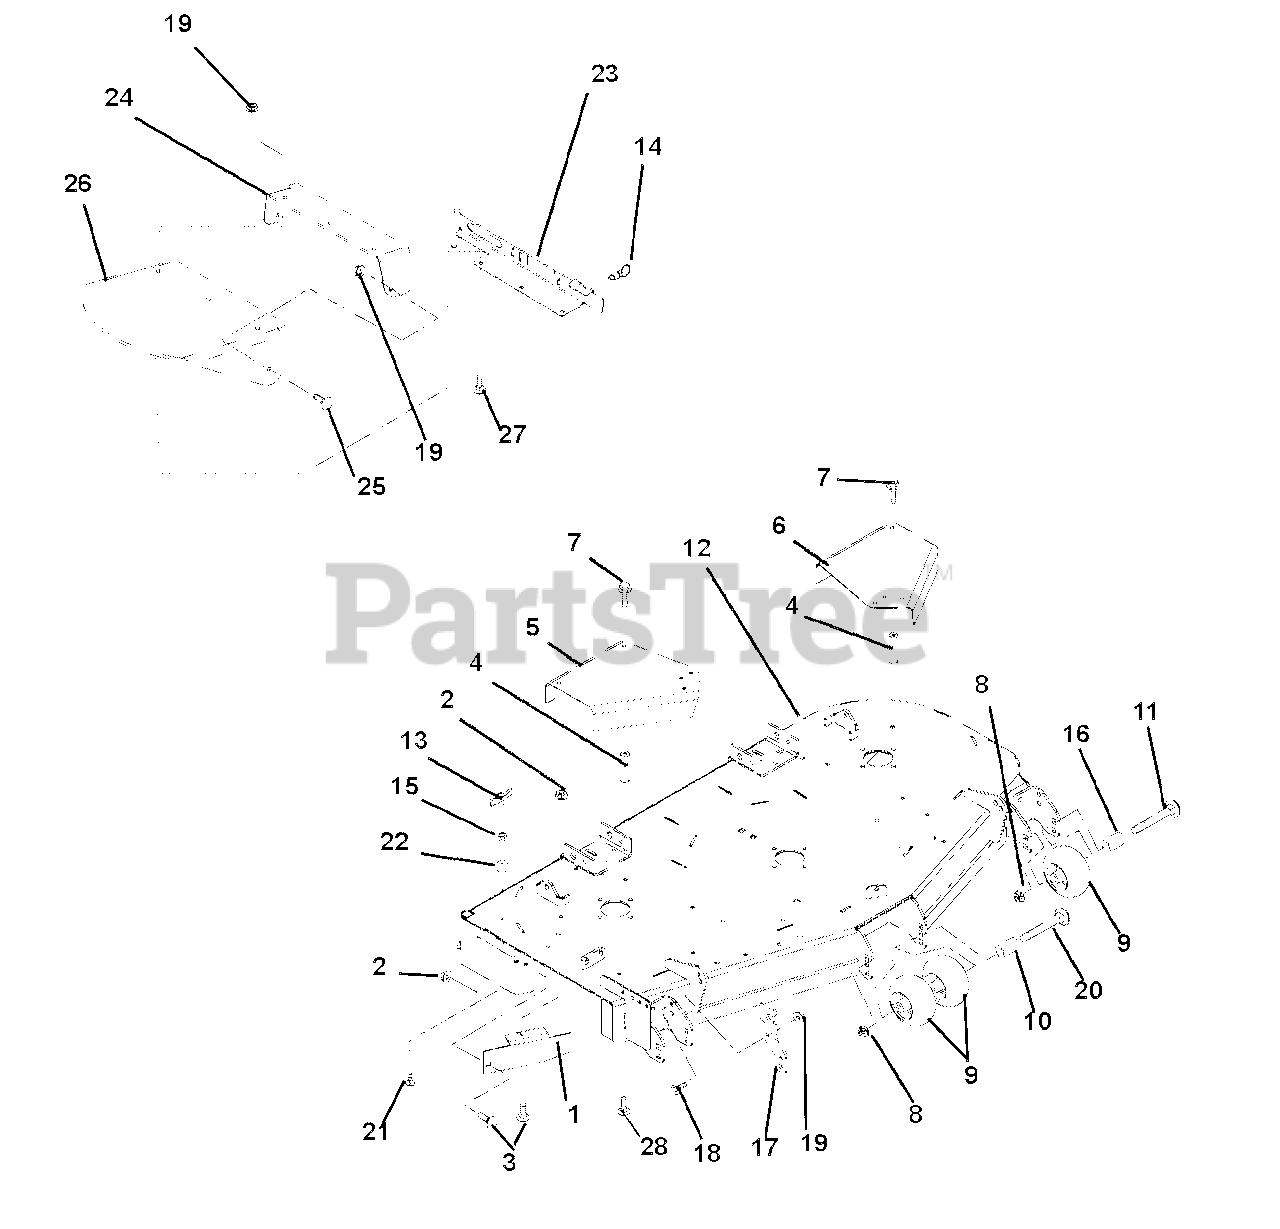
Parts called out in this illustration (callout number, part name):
1	60-in. Discharge Baffle
2	Nut, .31-18 Nyloc Flange
3	Bolt, Round Head Square Neck .31-18 x 1.00 Grade 5
4	Nut, Coupling .31-18 x 3.00
5	60-in. Right Hand Spindle Guard
6	60-in. Left Hand Spindle Guard
7	Bolt, SEMS .31-18 x .62
8	Nut .50-13 Nyloc Flange
9	Anti-Scalp Wheel
11	Bolt-Round Head Square Neck .50-13X5.00
12	60-in. Mower Deck
13	Knob, Wing .312-18
14	Pin, Plunger Pull .50-13 Thread x .310 Diameter
15	Nut, Locking, Center .31-18
16	Spacer, .510 x .625 x 3.35
17	Chute, Storage Bracket
18	Bolt, Hex .38-16 x 1.00
19	Nut, .38-16 Nyloc Flange
20	Bolt, Round Head Square Neck .50-13 x 8.50
21	Bolt, Round Head Square Neck .31-18 x 1.50
22	Bumper, Recessed 1.50 x .63 , .31 Thru Hole
23	52-inch and 60-inch Discarch Chute Mounting Weldment
24	Rubber Discharge Chute Support
25	Bolt, Round Head Square Neck .38-16 x 1.00 Grade 5
26	Chute, Rubber Discharge
27	Bolt, Round Head Square Neck .38-16 x 1.25 Grade 5
28	Bolt, round Head Square Neck .31-18 x .75
